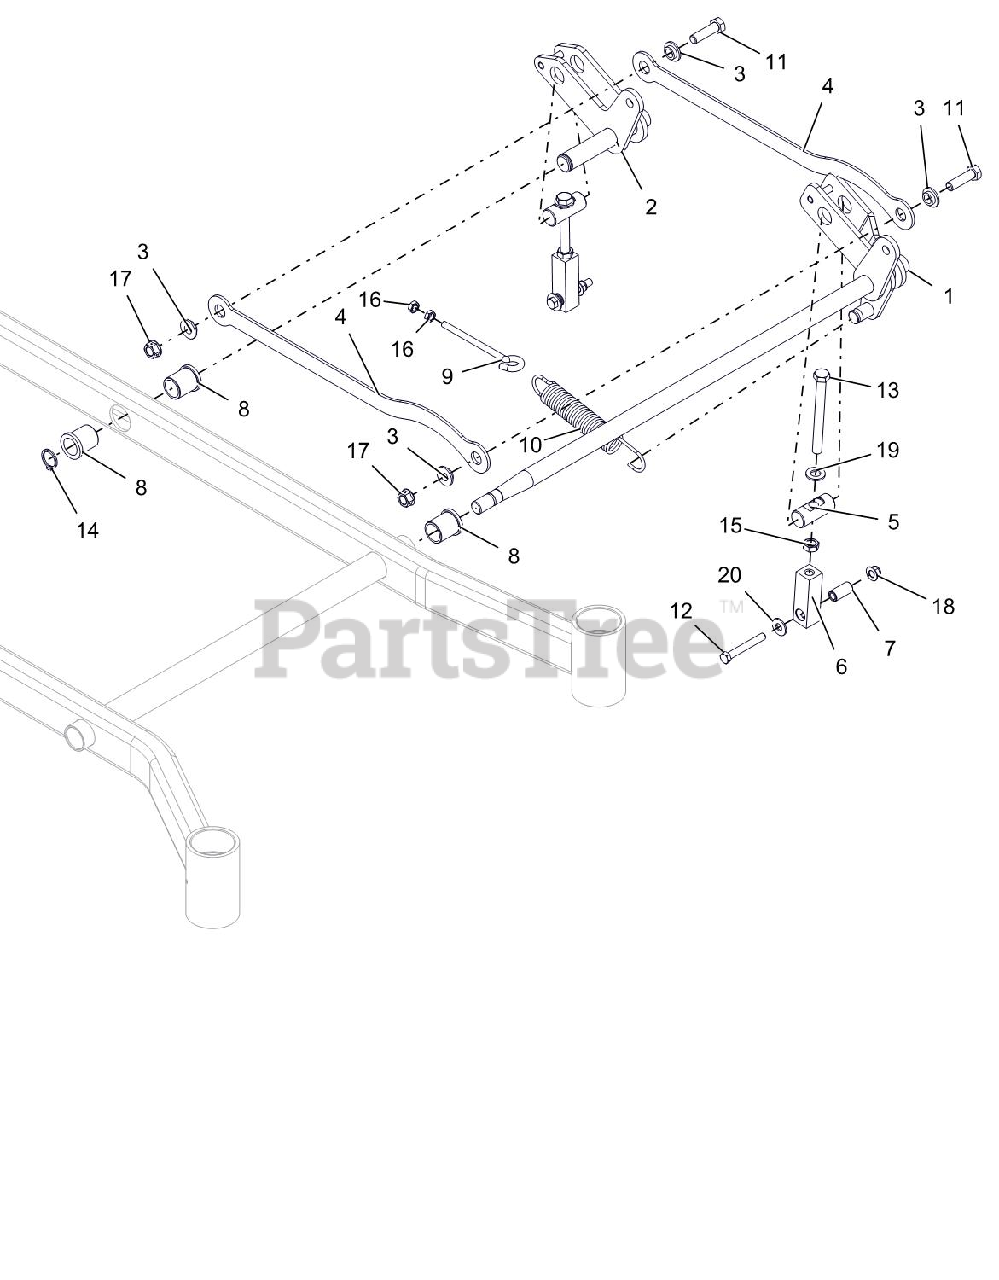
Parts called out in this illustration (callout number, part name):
1	WLDMT, FRONT
2	WLDMT, REAR LH DECK LIFT ARM (BLACK)
3	BSHG, FLANGE .515X.750X.31X1.12
4	LINK, LIFT
5	PIN, DECK LIFT
6	LINK, DECK LEVELING
7	SPCR, DECK LEVELING
8	BSHG-FLG 1.00X1.25X1.5X1.5
9	BOLT, EYE .38-16X6.00 .62 DIA
10	SPRG, TENSION .162 X 1.250 X 8.250
11	BOLT, HEX 0.5-13X1.75 GR5
12	BOLT, HEX 0.375-16X2.75 GR8
13	BOLT, HEX 0.5-13X5 GR5
14	RG-RTNG-EXT 1.00X.078
15	NUT, JAM .500-13 YWZC
16	NUT, JAM .375-16 YWZC
17	NUT-LK-CTR-FLG .50-13 YWZC
18	NUT-LK-NYL-FLG .38-16 YWZC
19	WSHR-FL-STL .557X1.040X.102 YWZC HARD
20	WSHR-FL-STL.438X1.00X.083 YWZC
